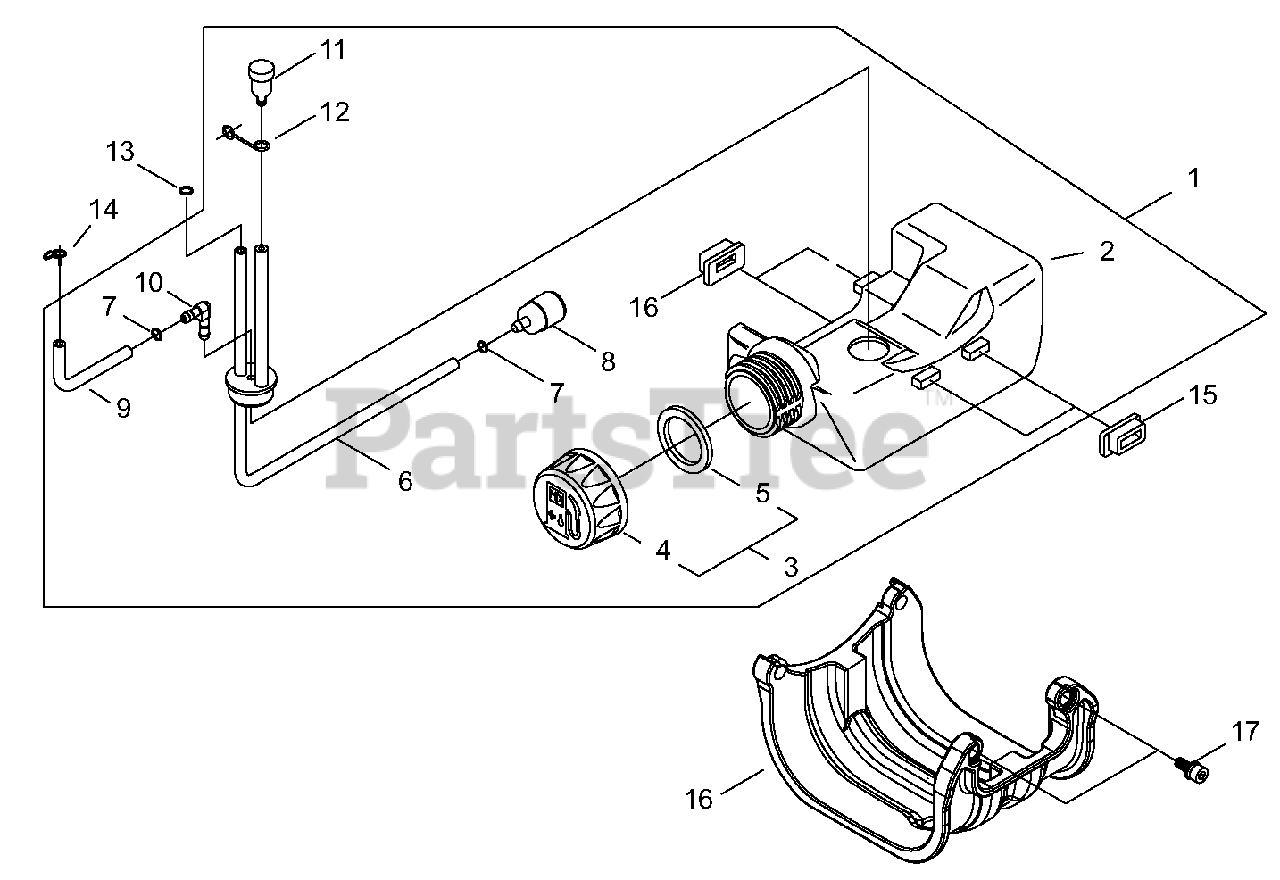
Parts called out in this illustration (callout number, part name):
1	TANK ASSY, FUEL
2	TANK, FUEL
3	CAP ASSY, FUEL
4	CAP, FUEL
5	GASKET, FUEL CAP
6	PIPE, FUEL
7	CLIP Ø6
8	FILTER, FUEL 125-528
9	PIPE, FUEL RETURN
10	CONNECTOR, PIPE
11	VENT ASSY
12	CLIP, VENT ASSY
13	CLIP Ø6
14	CLIP, SPRING Ø5.2
15	CUSHION, FUEL TANK
16	GUARD, PLASTIC FUEL TANK
17	BOLT M5×16
